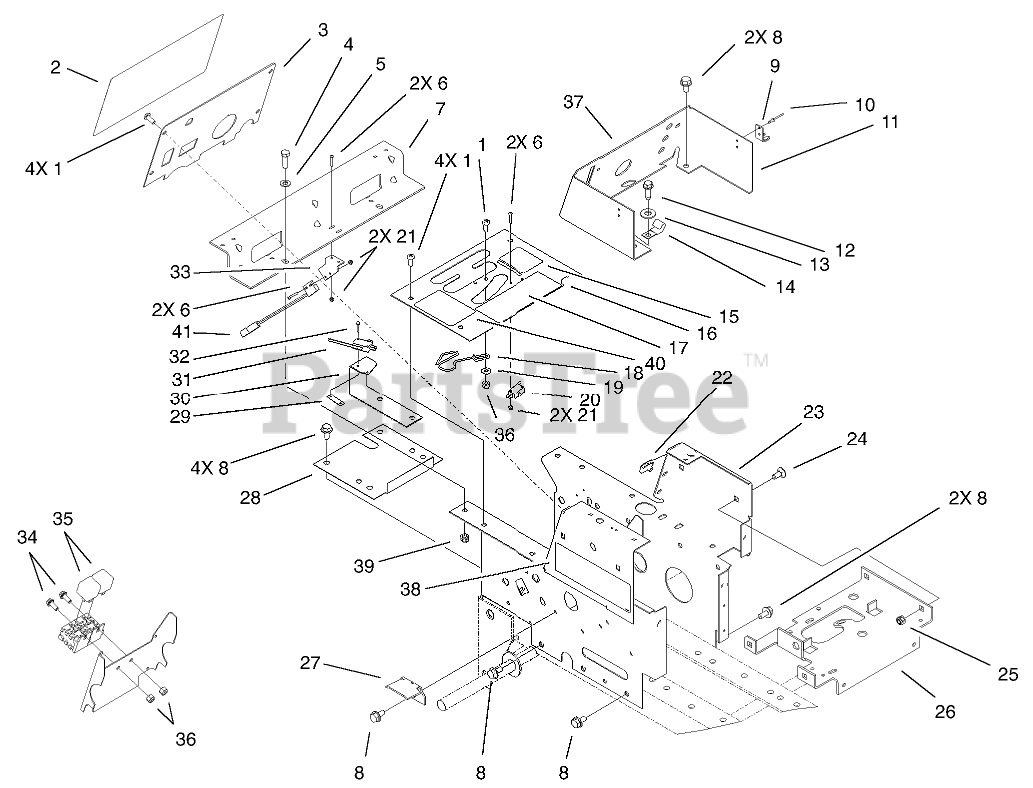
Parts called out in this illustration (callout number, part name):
1	SCREW-PPH
2	DECAL-DASH, LOWER
3	PLATE-HOODSTAND
4	SCREW-HH
5	WASHER-PLAIN
6	SCREW-PPH
7	BRACKET-FENDER
8	SCREW-HWHTF
9	KEEPER-LATCH
10	RIVET-POP
11	CONSOLE
12	SCREW-HWHTF
13	WASHER-FLAT
14	J-CLIP
15	DECAL-PARKING, BRAKE
16	PLATE-SHIFT
17	DECAL-DANGER
18	SPRING-SHIFT CONTROL
19	WASHER-FLAT
20	SWITCH
21	NUT-HEX
23	HOODSTAND ASM
24	BOLT-CARR
25	NUT-LOCK, NI
26	SUPPORT-BATTERY
27	BRACKET-BELT SUPPORT
28	COVER-DUST
29	NUT-SPEED
30	BRACKET-SWITCH, REVERSE
31	SWITCH-MICRO
32	SCREW-HH
33	BRACKET-SWITCH, REED
34	SCREW-HHF
35	RELAY
36	NUT-LOCK, NI
37	DECAL-CONSOLE
38	DECAL-MODEL 315-8
39	NUT-LOCK, NI
40	DECAL-SHIFT PATTERN
41	SWITCH-REED, MAGNETIC
